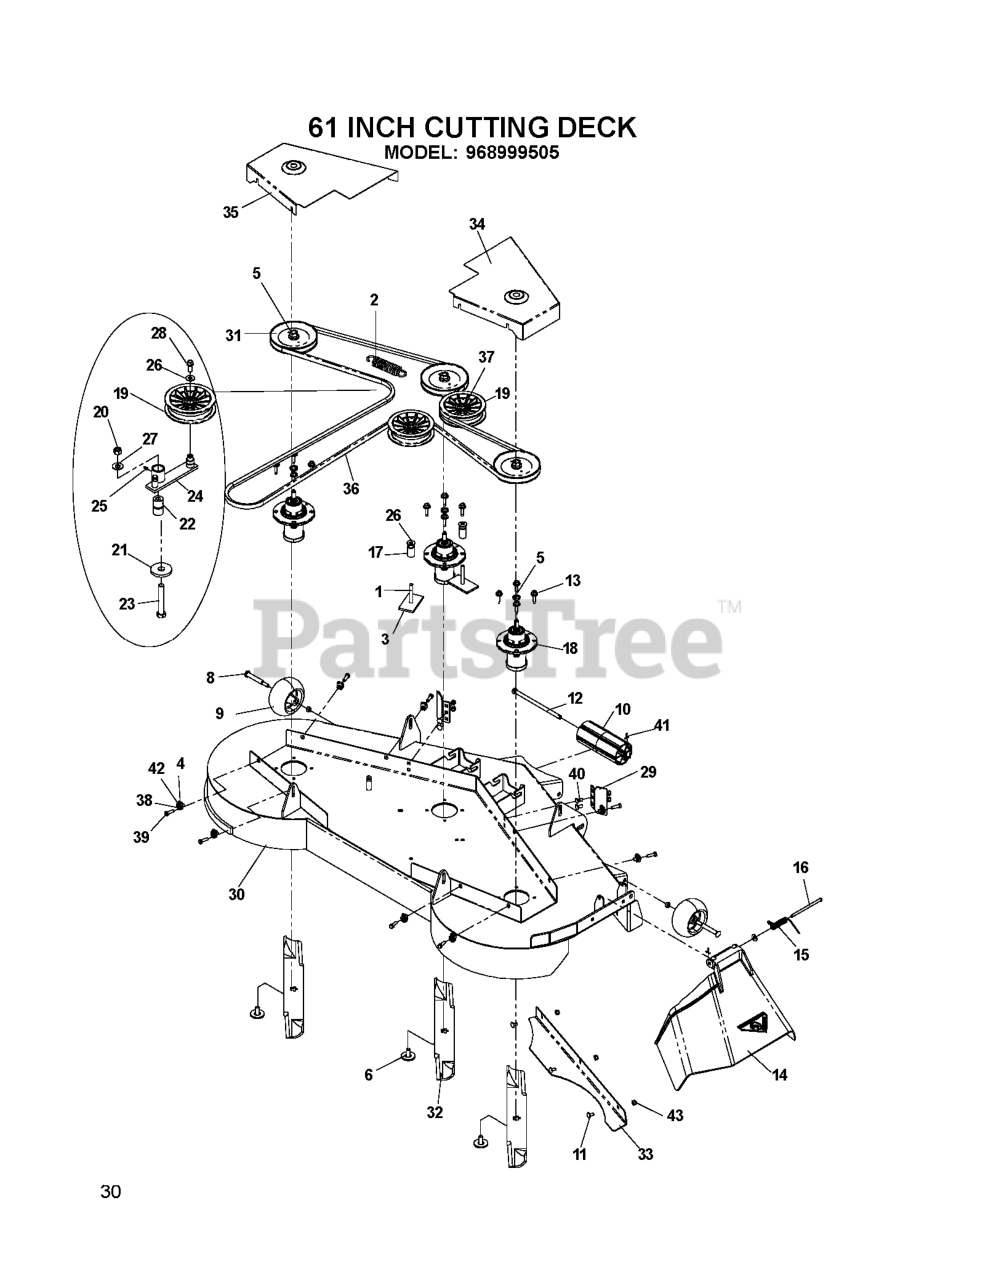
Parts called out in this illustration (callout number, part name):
1	HCS 3/8C X 3
3	SUPPORT PLATE
4	U-CLIP 5/16-18 NUT RETAINER
5	WASHER-SPACER
6	BLADE BOLT ASSY-7/16" TB REPL
7	LOCKNUT - 9/16
8	SHOULDER BOLT 1/2X2-5/8 ZD SPE
9	GAUGE WHEEL
10	NOSE ROLLER-48"
11	CARRIAGE BOLT 5/16C X 5/8"
12	NOSE ROLLER ROD
13	WASHER HEAD SCREW
14	DISCHARGE CHUTE 61"
15	SPRING - TORSION
16	PIN-CLEVIS 5/16 DIA X 5.19 ZD
17	IDLER BUSHING
18	MANDREL.DECK.ASSEMBLY
19	IDLER
20	NUT 1/2-13 HEX NYLOC ZD
21	WASHER, SUPPORT
22	PIVOT BUSHING
23	HCS 1/2C X 3 1/4
25	ZERK
26	WASHER 3/8 FLAT
27	WASHER 1/2 FLAT
28	4CS 3/8C X 1 SERRATED HEAD
30	DECK W/DECALS 61" HUS
32	BLADE, 21"
33	CONFINEMENT PLATE 61
34	BELT SHIELD W/DECALS, 61" RT
35	BELT SHIELD W/DECALS,61" LT
36	BELT, DECK - ESTATE
37	NUT 3/8-16 NYLOC
38	WASHER.LOCK.HVY.HLCL.SPR.5/16
39	HCS 5/16C X 1
40	BOLT 5/16C X 3/4" CARRIAGE
41	RP_COTTER PIN 1/8 X 3/4
42	WASHER 5/16 FLAT
43	NUT 5/16 NYLOC
